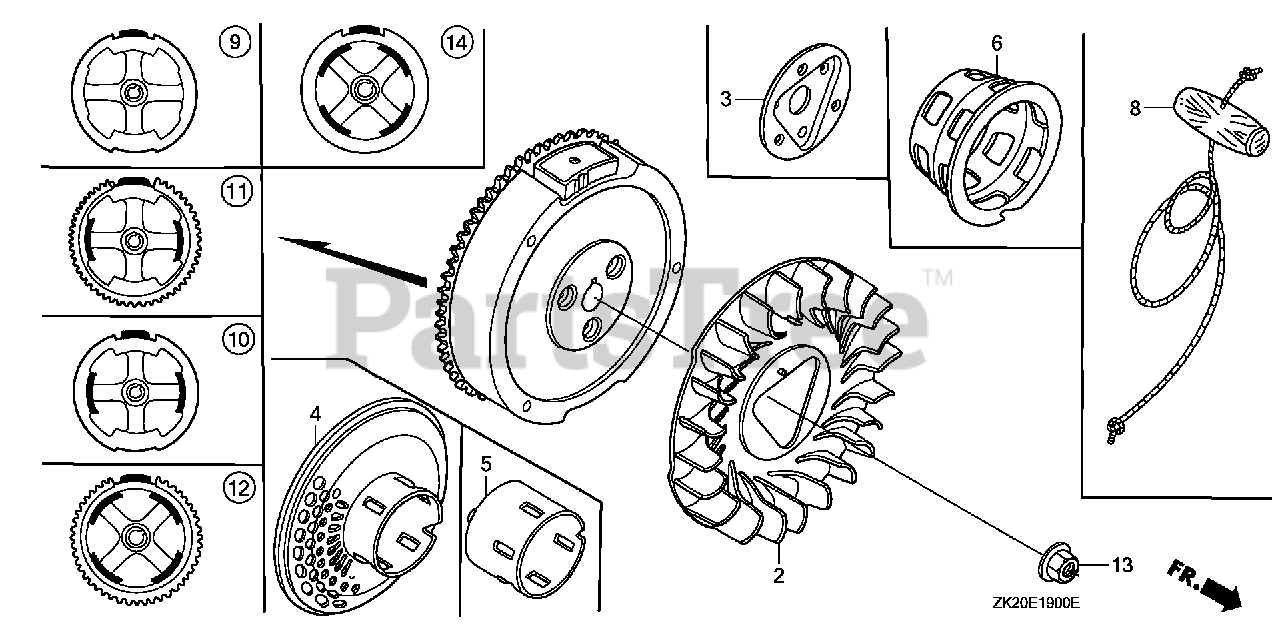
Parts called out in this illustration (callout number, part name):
2	FAN, COOLING
4	PULLEY, STARTER (SCREEN GRID)
13	NUT, SPECIAL (16MM)
